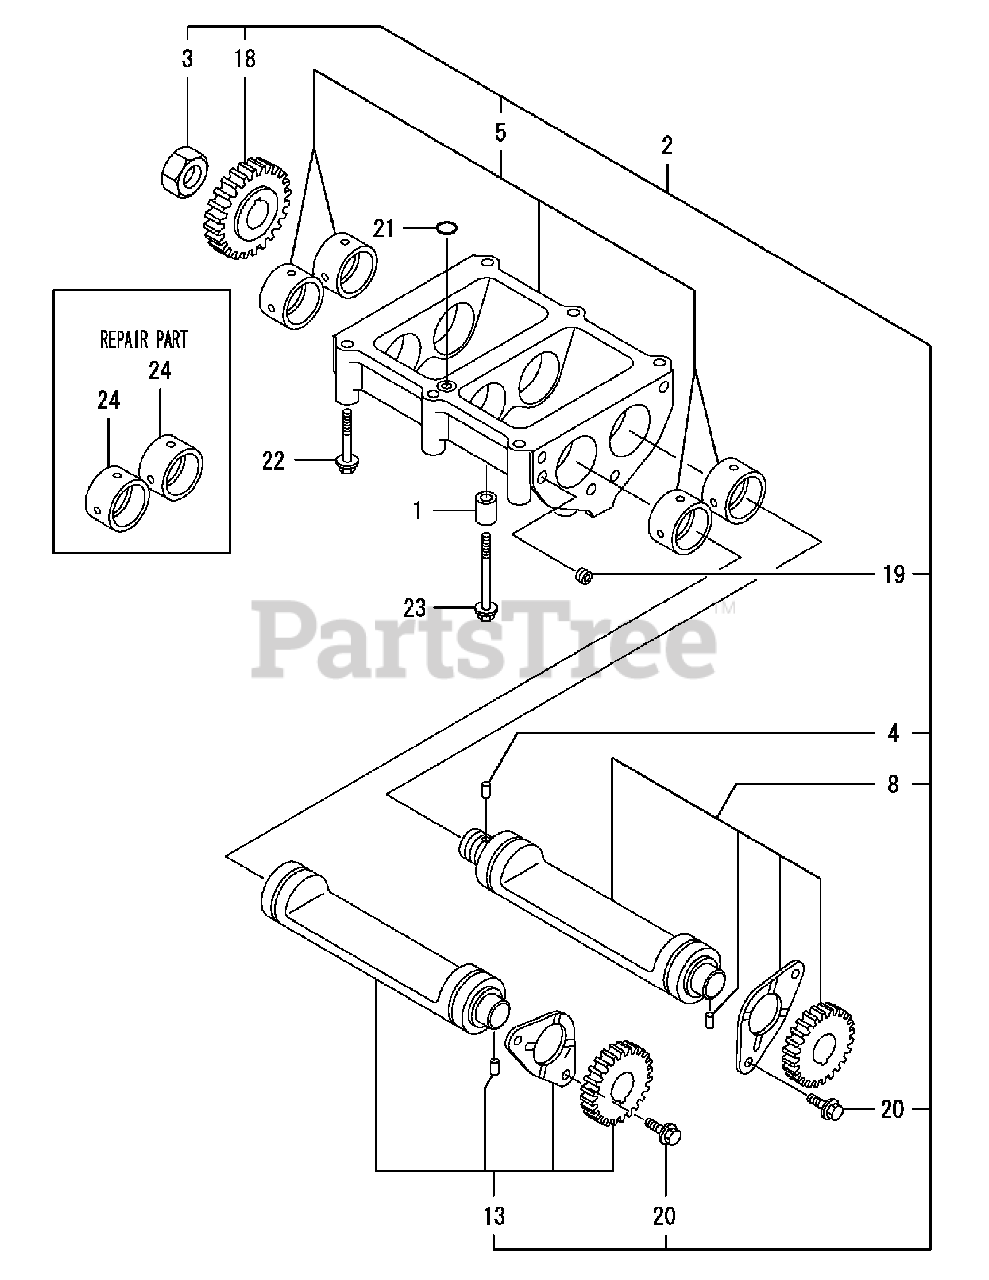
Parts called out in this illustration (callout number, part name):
5	CASE ASSY, BALANCER
8	SHAFT, BALANCER A
13	SHAFT, BALANCER B
18	GEAR, BALANCER A
20	BOLT 8X 14 PLATED
21	O-RING 1A P-14.0
22	BOLT M 8X 60 PLATED
23	BOLT M 8X 80 PLATED
